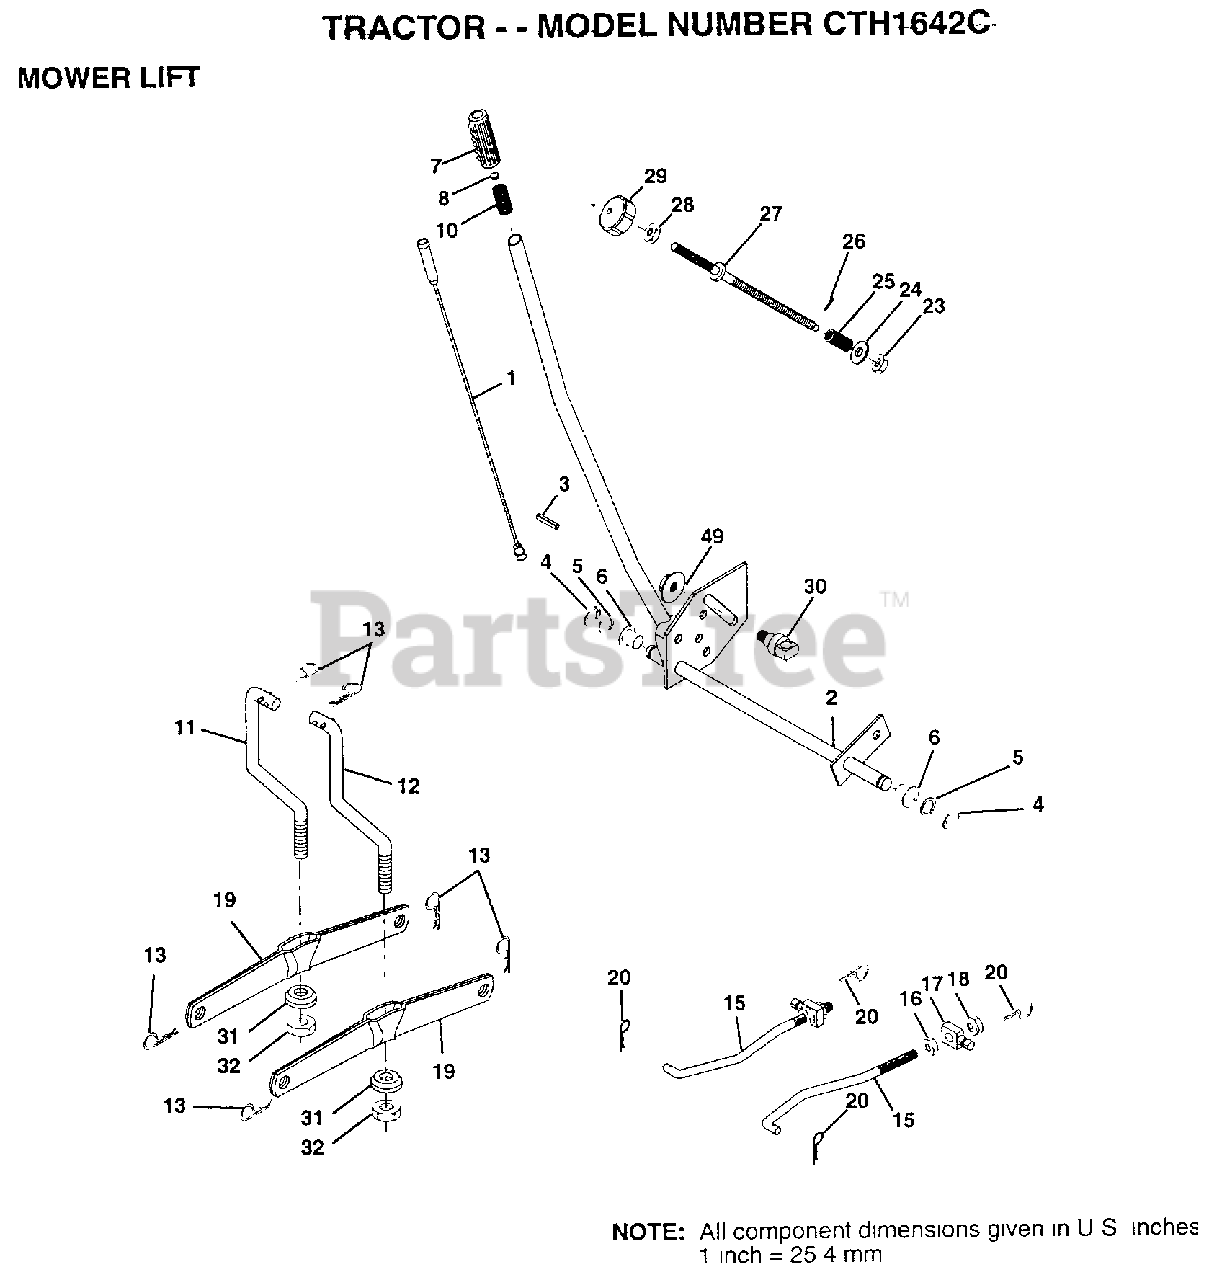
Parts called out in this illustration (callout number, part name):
1	WIRE ASM
2	SHAFT.ASM.LIFT
3	PIN GROOVE
5	WASHER
6	NYLON BEARING
7	GRIP
15	LINK.FRONT
16	NUT
17	TRUNION
18	NUT.LK.W/WSH.1/2.
19	ARM SUSP REAR
20	RETAINER.SPRING
23	NUT T
24	WASHER
25	SPRING.COMP.INF.H
27	ROD.ADJ.LIFT
28	NUT
29	KNOB INF 3/8-16
30	TRUNNION
31	BEARING PVT LH
32	NUT.CROWNLOCK.3/8
49	NUT.HXFLG.LOCK.
